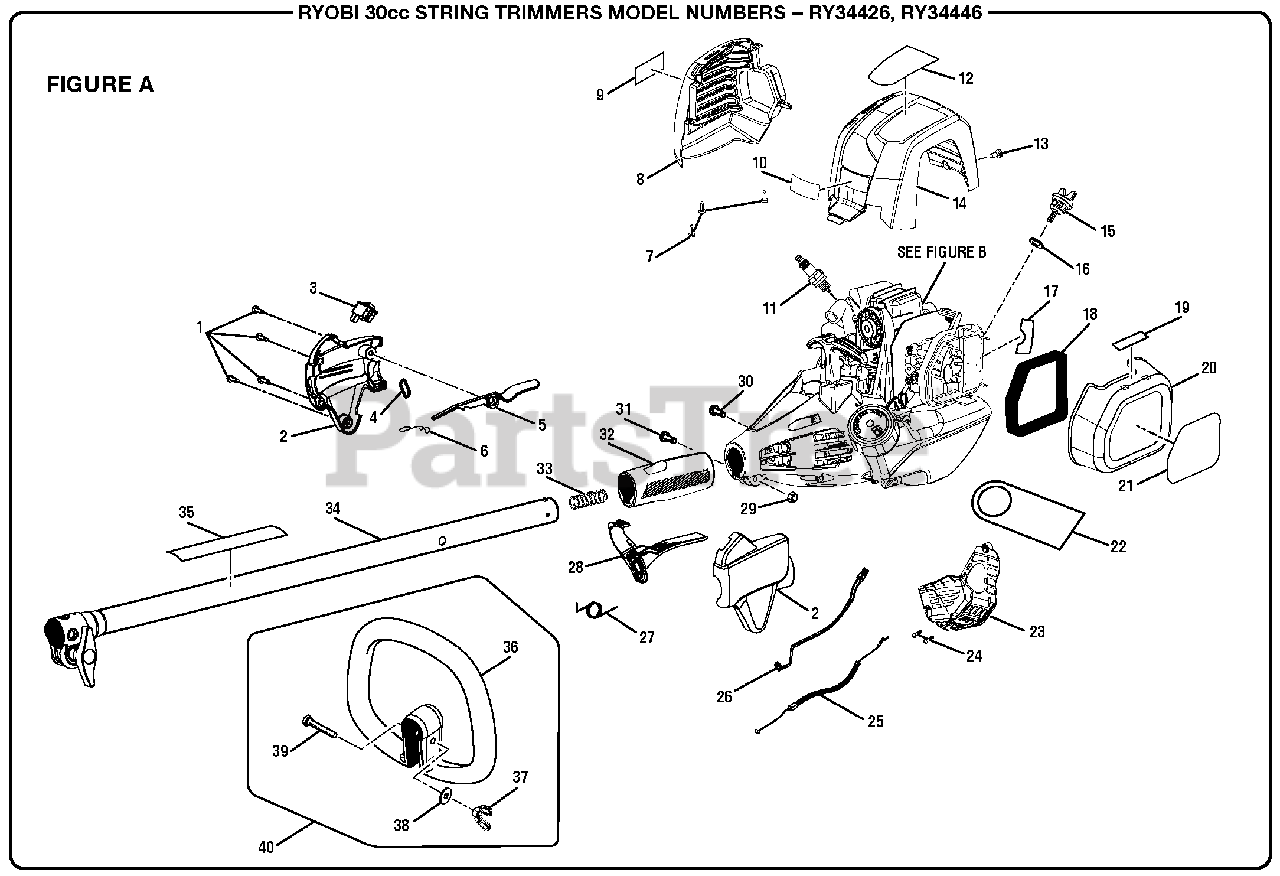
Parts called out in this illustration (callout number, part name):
1	Screw (M4 x 20 mm, T20 Torx Pan Hd.)
2	Control Handle Assembly
3	Switch (Momentary Contact)
4	Strap Hanger
5	Trigger Lock
7	Screw (M4 x 12 mm, T20 Truss Hd.)
8	Muffler Housing
9	Combustion Warning Label
10	Logo Label
11	Spark Plug (Champion RY4C)
12	X430 Label (RY34006)
13	Shoulder Screw (M4 x 11 mm, T20 Torx Pan Hd.)
14	Top Cover
15	Oil Cap/Dipstick
17	Hot Surface Label
18	Air Filter
19	Choke Label
20	Air Filter Cover
21	Starting Label
22	Oil Hang Tag
23	Bottom Cover
24	Screw (#6-19 x 1/2 in., Phillips Hd. T.F.)
25	Throttle Cable
26	Lead Assembly
27	Torsion Spring (Throttle Trigger)
28	Throttle Trigger
29	Hex Nut (M6.3 x 1)
30	Screw (#8-16 x 5/16 in., T25 Torx Pan Hd. T.F.)
31	Bolt (M6 x 20 mm, T27 Torx Button Hd.)
32	Rear Handle
33	Compression Spring
34	Upper Boom Assembly
35	Warning Label
36	Front Handle
37	Wing Nut (1/4-20)
38	Washer (ID7 x OD19 x 1-3/4t)
39	Screw (1/4-20 x 40 mm, Hex Hd.)
40	Front Handle Assembly
